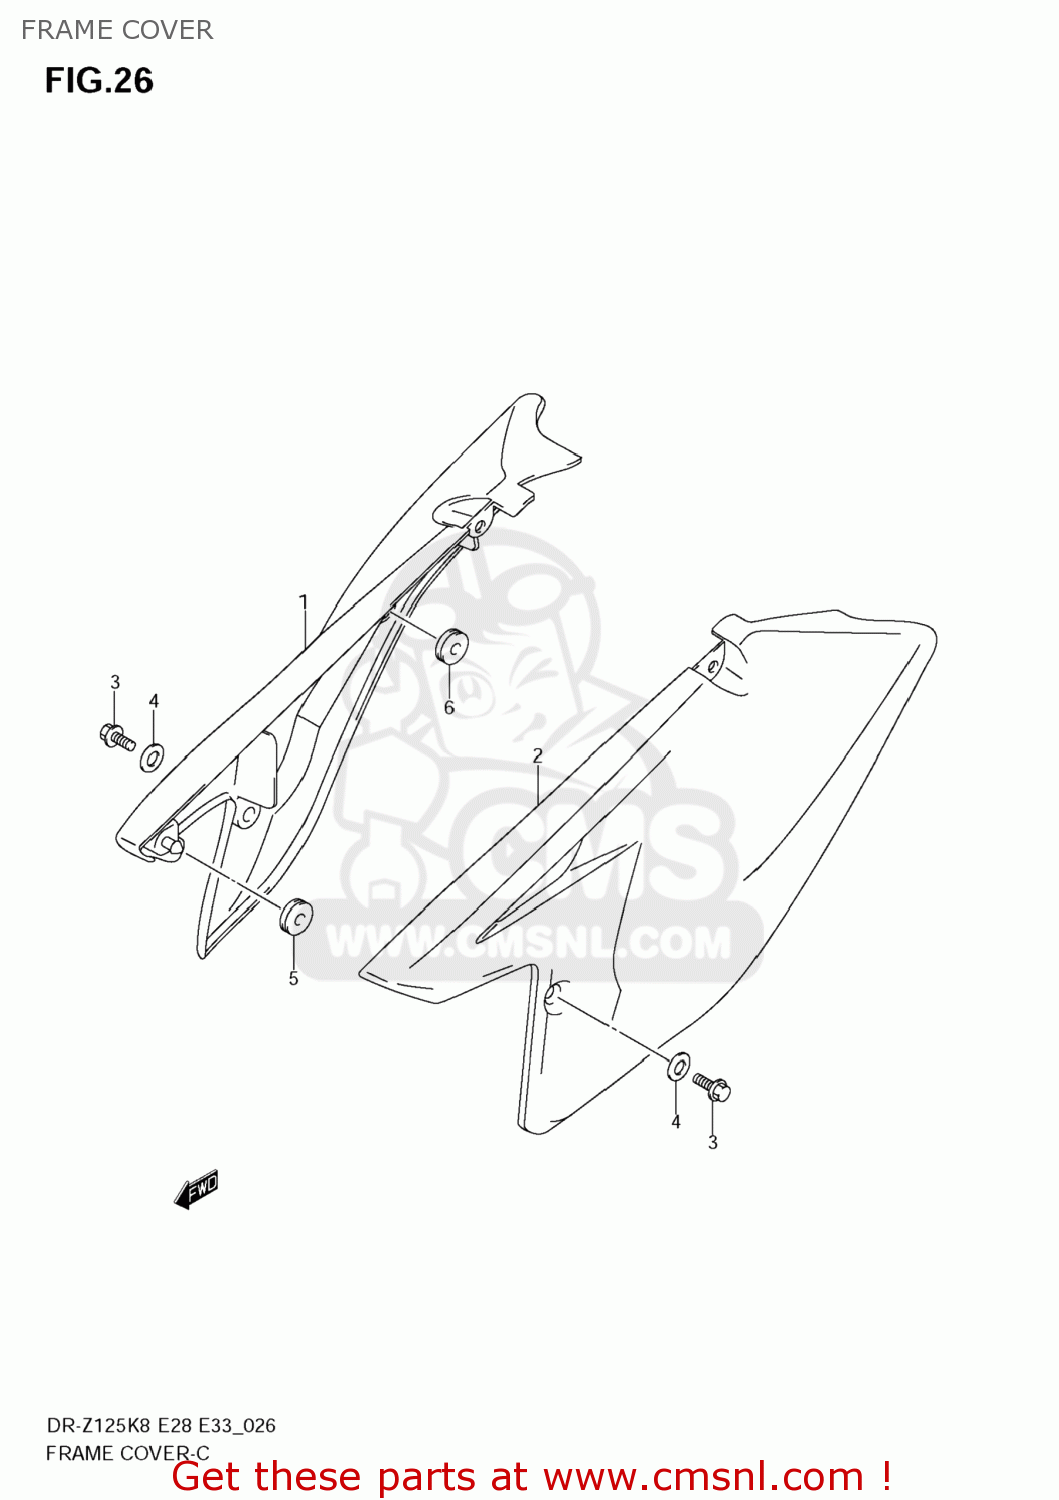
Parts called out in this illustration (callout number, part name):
1	COVER,FRAME,R(WHITE)
2	COVER,FRAME,L(WHITE)
3	BOLT
4	WASHER
5	CUSHION
6	CUSHION
